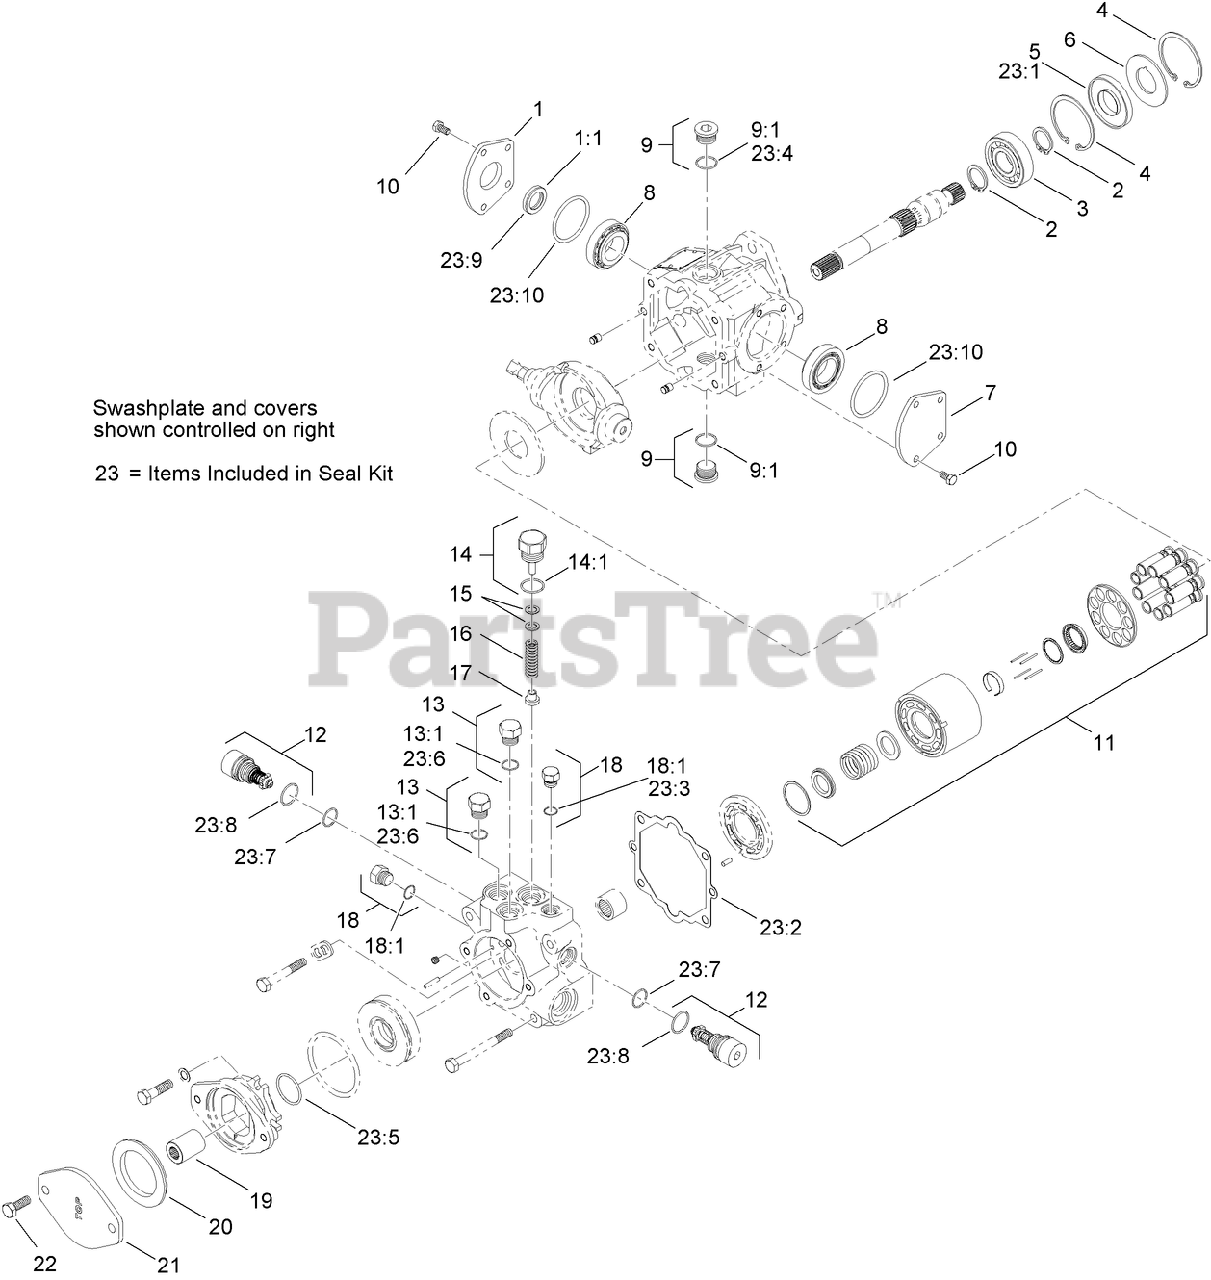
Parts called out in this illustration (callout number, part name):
1	TRUNNION COVER ASM
1:1	SEAL-LIP
2	RING-RETAINING
3	BEARING-BALL
4	RING-RETAINING
5	SEAL-LIP
6	WASHER-BACKUP
7	COVER-TRUNNION
8	BEARING KIT
9:1	O-RING
11	CYLINDER BLOCK KIT
12	VALVE-SOLENOID, CHECK
13	PLUG
13:1	O-RING
14	PLUG-RELIEF, CHARGE
14:1	O-RING
15	SHIM KIT
16	SPRING
17	POPPET-RELIEF, CHARGE
18	PLUG ASM
18:1	O-RING
19	COUPLING
20	SEAL-A, PAD
22	SCREW
23	SEAL KIT
23:1	Seal-Lip
23:2	Gasket-End Cap
23:3	O-RING
23:4	O-RING
23:5	O-RING
23:6	O-RING
23:7	O-RING
23:8	R-RING
23:9	Seal-Lip
23:10	O-RING
